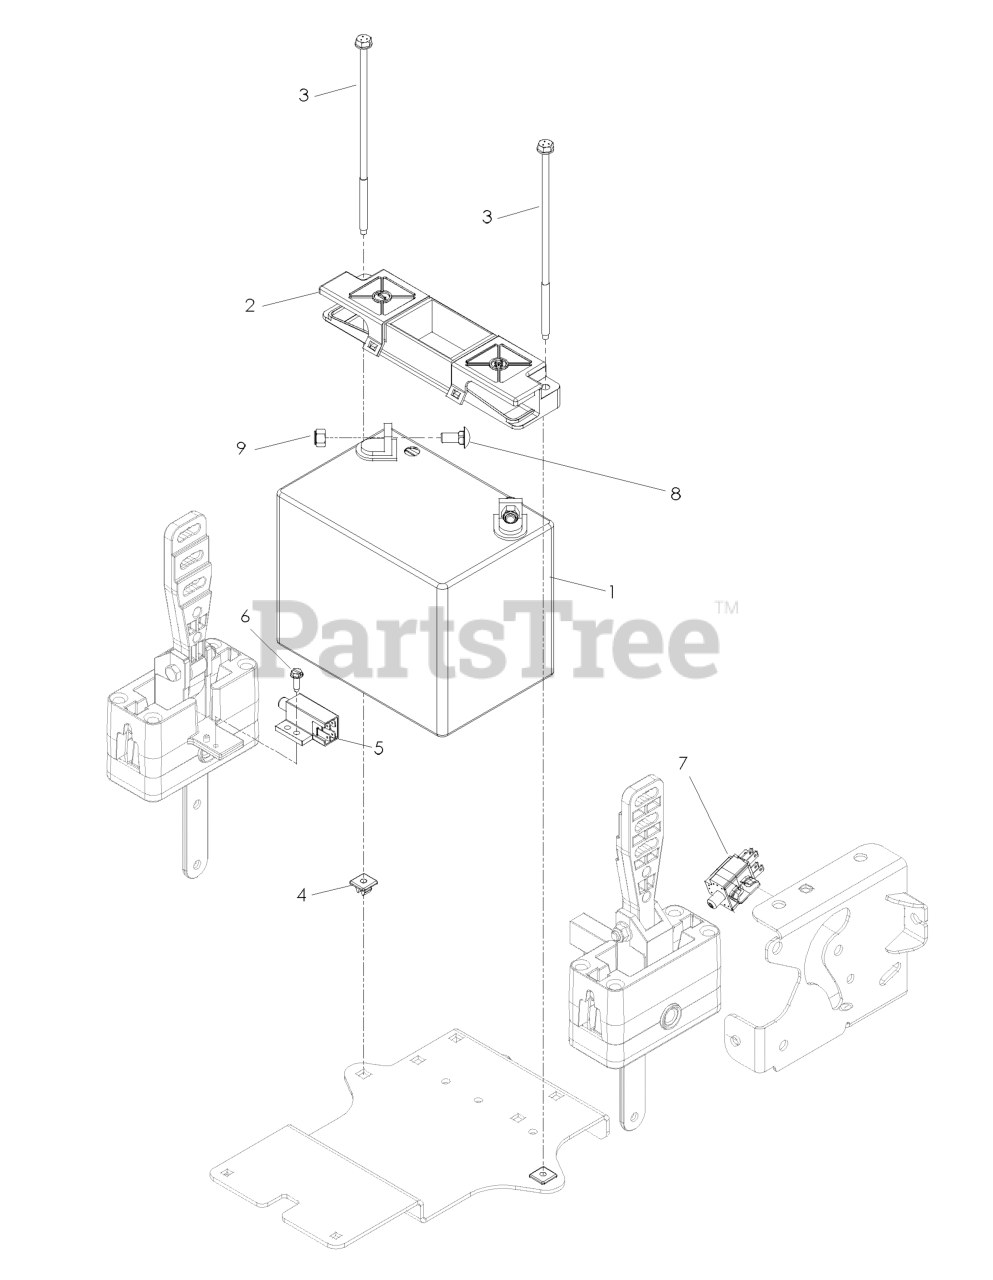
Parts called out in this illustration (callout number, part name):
1	BATTERY, 12 V 330 AMP TBR
2	BATTERY HOLD DOWN
3	BOLT - 1/4-20 X 7.5
4	PUSH NUT-NYLON
5	SWITCH, INTERLOCK
6	SCREW #10 X 1/2 SELF TAPPING
7	SWITCH, BRAKE 3P
8	BOLT 5/16C X 3/4" CARRIAGE
9	5/16-18 NYLOC FLANGE NUT
